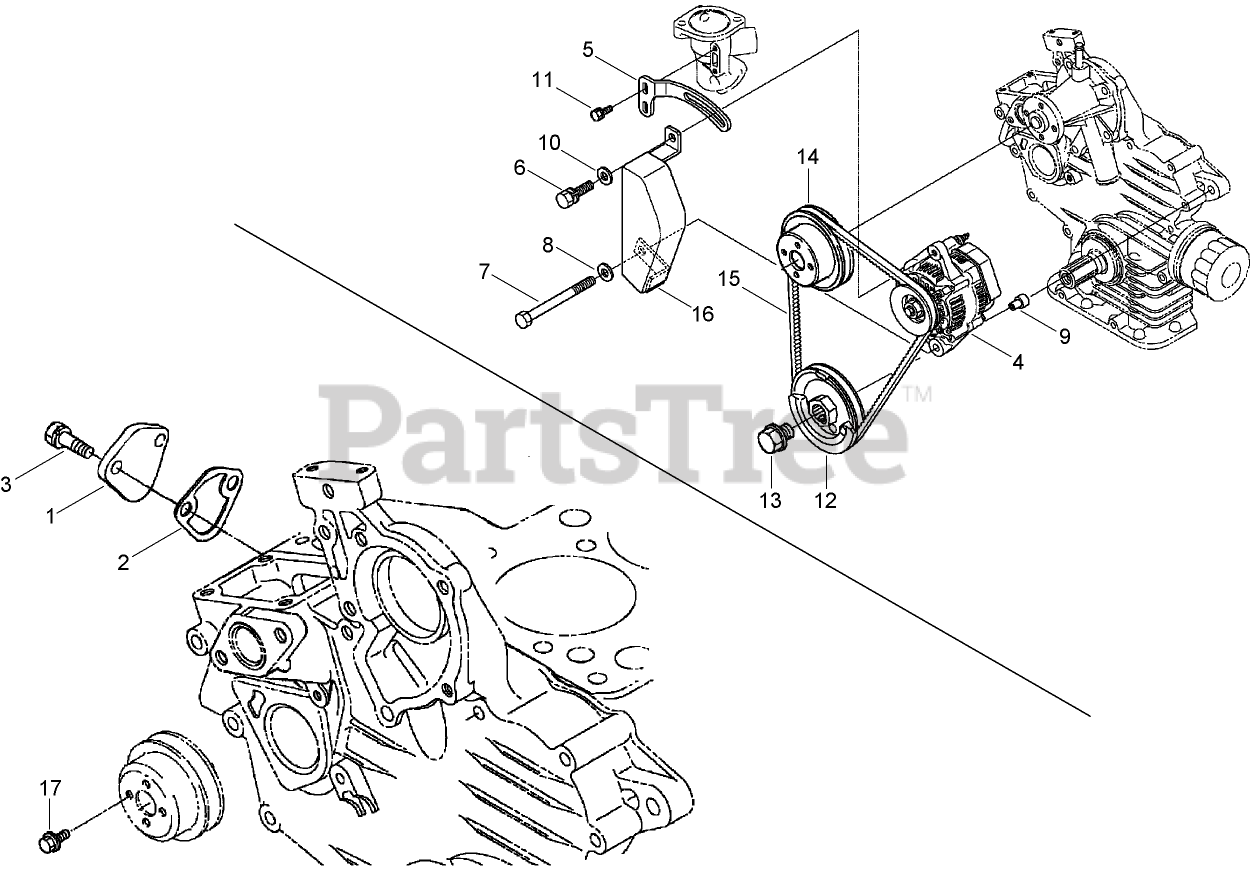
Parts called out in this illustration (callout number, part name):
1	COVER
2	GASKET-PUMP, FUEL
4	ALTERNATOR ASM
5	STAY-ALTERNATOR
8	WASHER-PLAIN
9	COLLAR
10	WASHER-PLAIN
12	PULLEY-DRIVE, FAN
14	PULLEY-FAN
15	BELT-V
17	BOLT-FLANGE
